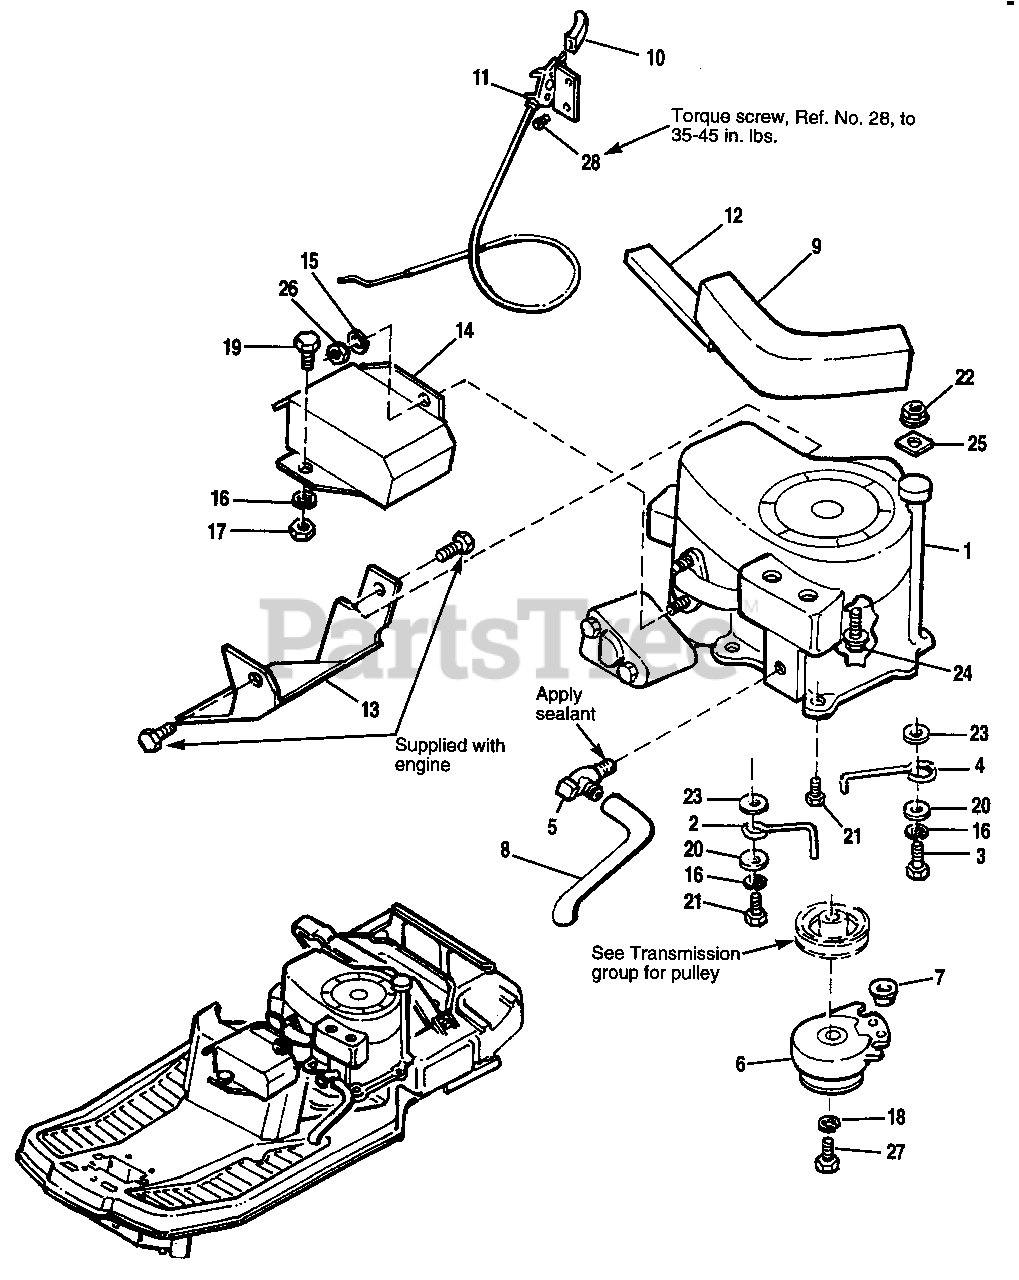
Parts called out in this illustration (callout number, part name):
1	ENGINE, 12 HP (Tecumseh)
3	SCREW, Taptite, 3/8-16 x 2
5	VALVE, Oil Drain
6	CLUTCH, Electric
7	SLEEVE, Clutch Anchor
8	HOSE, Oil Drain
9	SEAL, Air Inlet
10	KNOB, Throttle Control
11	THROTTLE CONTROL ASSY.
13	DEFLECTOR, Air, Lower
14	SHIELD, Muffler
15	LOCKWASHER, 1/4
16	LOCKWASHER, 5/16
17	NUT, Hex, 5/16-18
18	LOCKWASHER, 7/16
19	CAPSCREW, Hex, 5/16-18 x 3/4
20	WASHER, Plain, 3/8
21	SCREW, Taptite, 3/8-16 x 1-1/2
22	NUT, Hex, Flange, Whizlock, 5/16-18
23	WASHER, Plain
24	SCREW, Hex, Flange, Whizlock, 5/16-18 x 1-1/2
25	PUSH NUT, 5/16
26	NUT, Hex, 1/4-28
27	CAPSCREW, Hex, 7/16-20 x 2-1/2
28	SCREW, Plastite, 1/4-10 x 1/2
